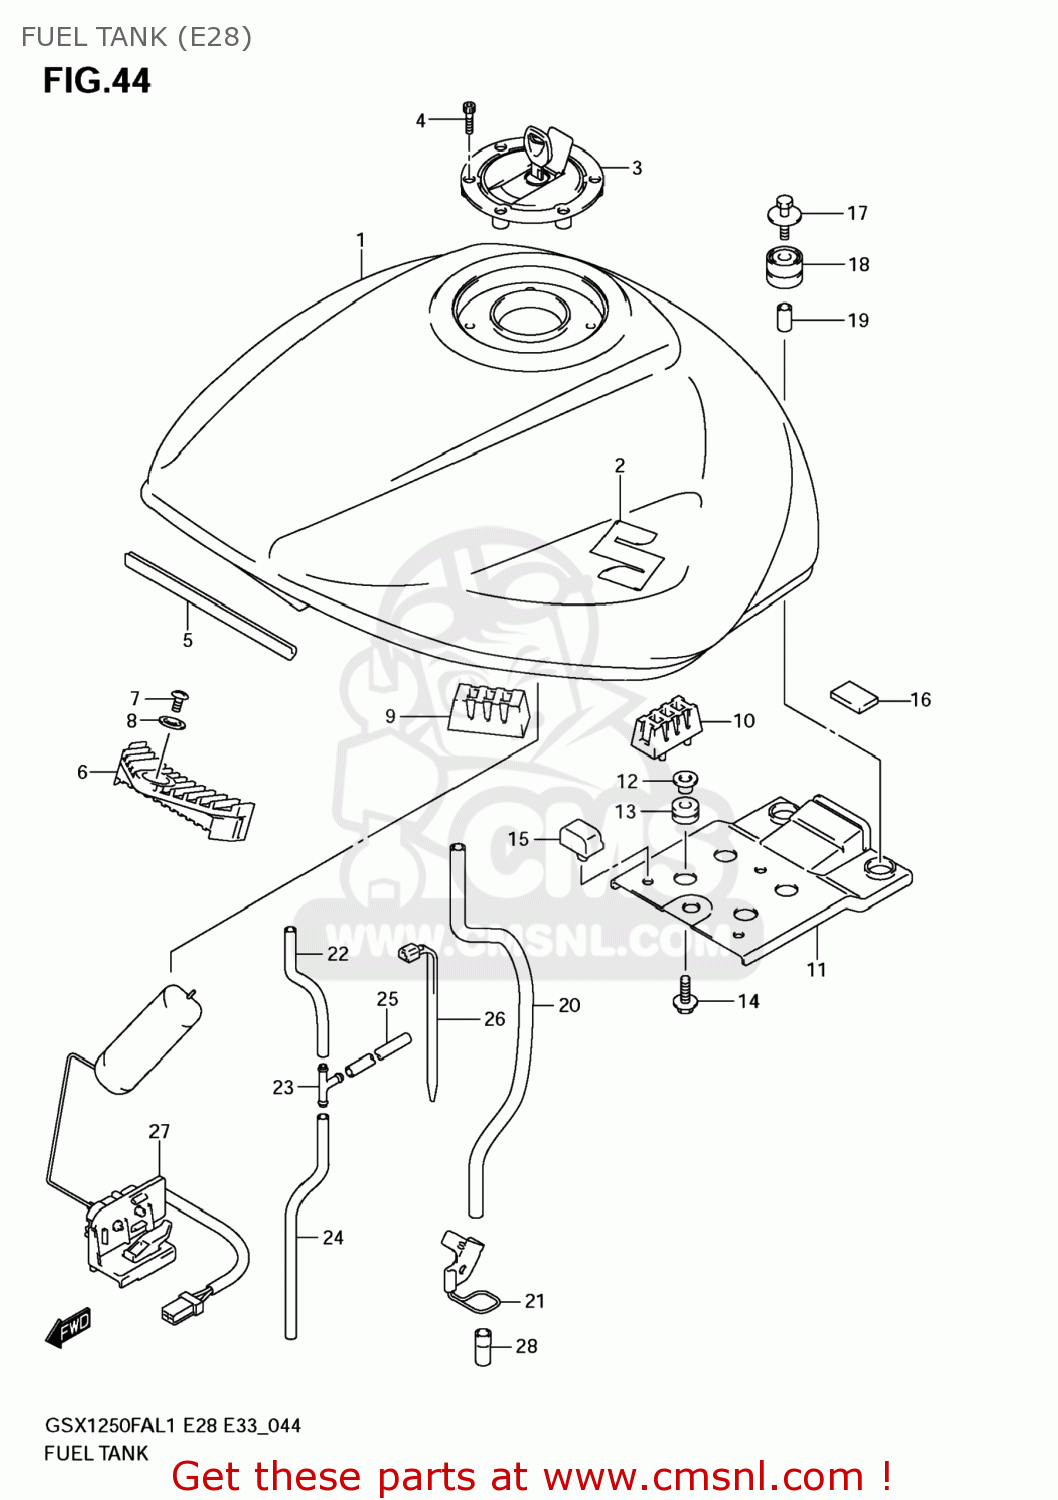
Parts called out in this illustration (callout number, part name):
1	TANK ASSY,FUEL
2	EMBLEM,S
3	CAP SET,FUEL TANK
4	BOLT(5X20)
5	MOLDING
6	CUSHION,FUEL TANK FR
7	SCREW
8	WASHER
9	CUSHION,SUPPORT(50X25X32)
10	CUSHION,TANK SIDE
11	BRACKET,FUEL TANK RR
12	WASHER
13	CUSHION
14	BOLT(6X20)
15	CUSHION
16	CUSHION,SIDE COVER BRACKET
17	BOLT(6X30)
18	CUSHION,FUEL TANK RR BRKT
19	SPACER(6.5X9X18)
20	HOSE,FUEL TANK DRAIN
21	GUIDE,DRAIN HOSE
22	HOSE,VACUUM
23	JOINT,3 WAY
24	HOSE(5X8.2X600)
25	HOSE(5X8.2X2000)
26	CLAMP(L:125)
27	GAUGE ASSY,FUEL LEVEL SENDER
28	HOSE(13.5X16.5X10)
